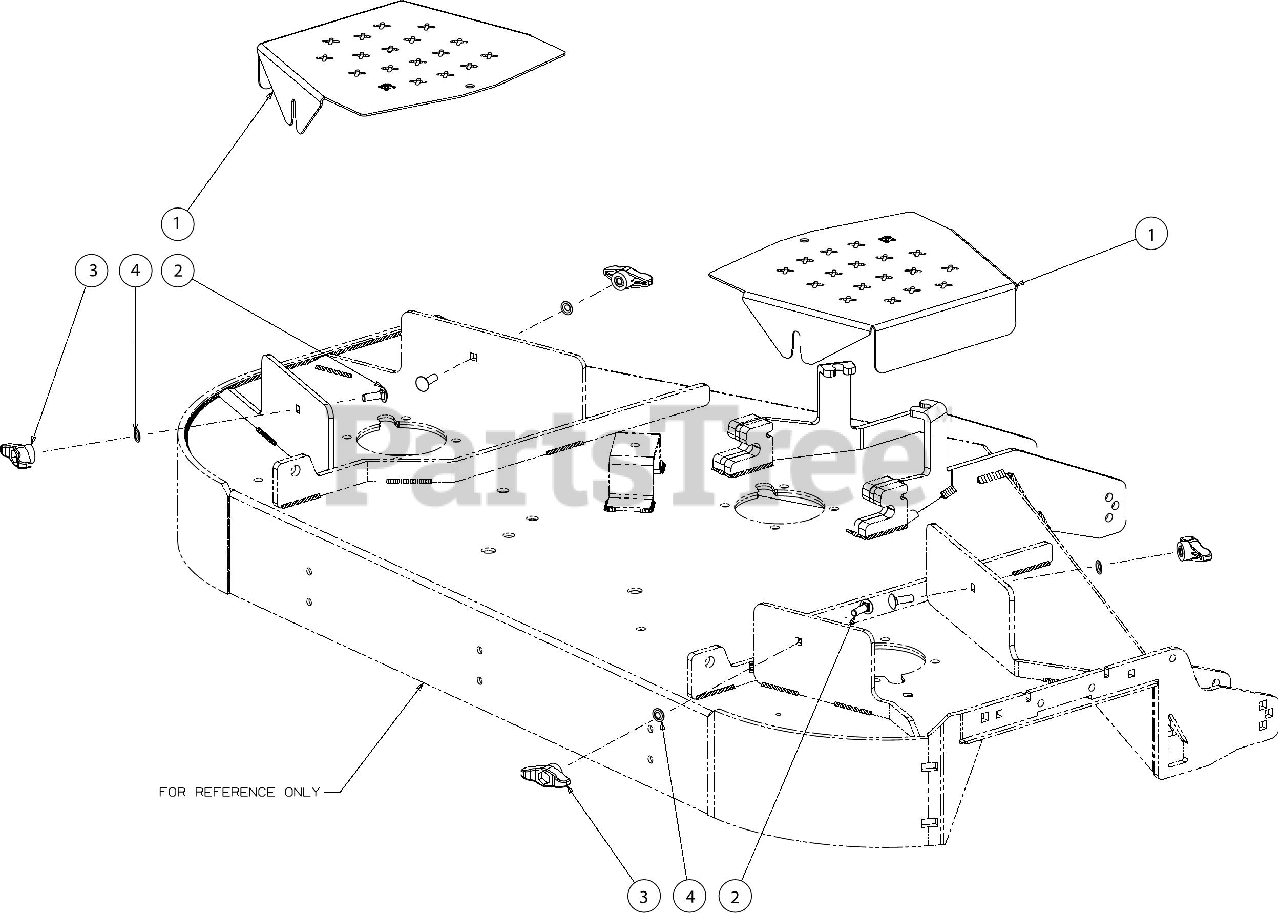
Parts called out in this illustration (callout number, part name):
1	BELT COVER
2	CARRIAGE BOLT 5/16-18 X 1.00
3	WING KNOB 5/16-18
